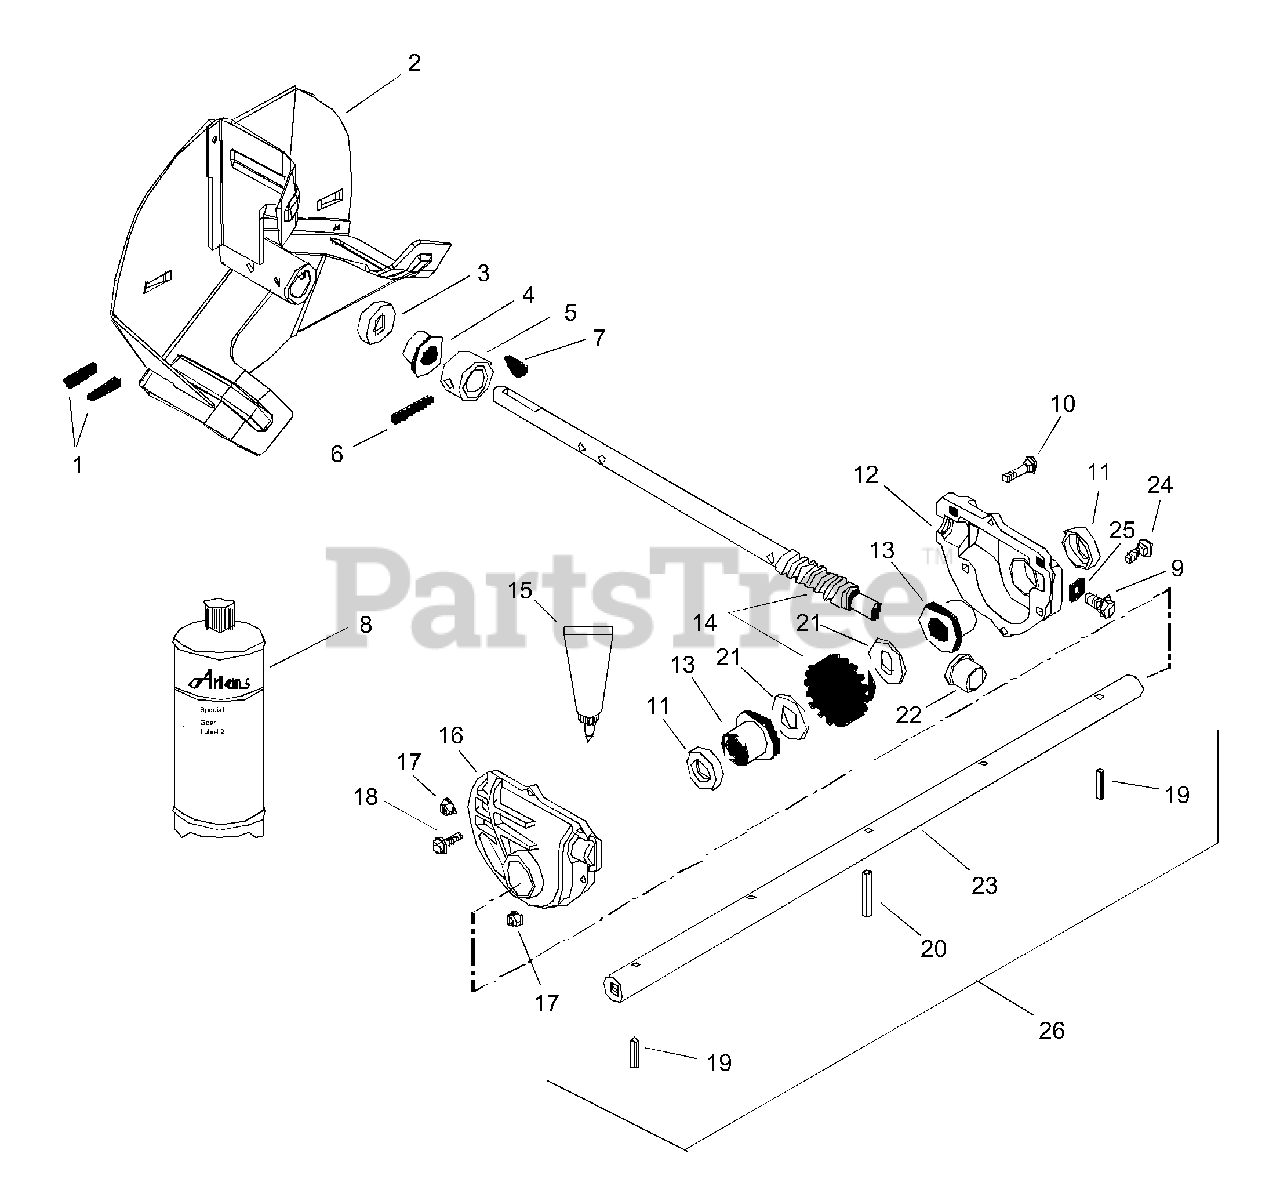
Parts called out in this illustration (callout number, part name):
1	PIN-ROLL .250X1.75
2	IMPELLER - .75 ID X 12" OD
3	SEAL-OIL .750X1.375X.250
4	BSHG-FLG .750X1.000X.750X1.250
5	THRUST COLLAR
6	PIN-GRV .188X1.25 TP A
7	KEY-WDRF .188X.875X.375 SAE11
8	ARIENS 16 OZ.BOTTLE OF L2 LUBE
9	@SCR-TAP .38-16X.50 HWH TR YWZ
10	@BLT-RDHDSQNK .25-20X1.25 G5YZ
11	SEAL-OIL 1.000X1.375X.250
12	CASE, GEAR-LH-LARGE BORE-ALUM.
13	BSHG-FLG 1.00X1.12
14	WORM SHAFT & GEAR ASSY
15	LOCTITE GASKET 518--850CC CRTG
16	CASE, GEAR-RH-LARGE BORE-ALUM.
17	@NUT-SPNLK-FLG .25-20 YWZC
18	SCR-TAP 10-24X.75 HWH TR YWZC
19	PIN-ROLL .188X1.50
20	PIN-GRV .313X1.44 TP C
21	WSHR-HRD-THRS 1.007X1.542X.062
22	BSHG-FLG .502X1X.750
23	SHAFT, RAKE - 24"
24	BLT-RDHDSQSHK .25-20X.88 GR5YW
25	WSHR-FIBER .437X.656X.032
26	GEAR CASE-LRG BORE-ALUM.- 24"
